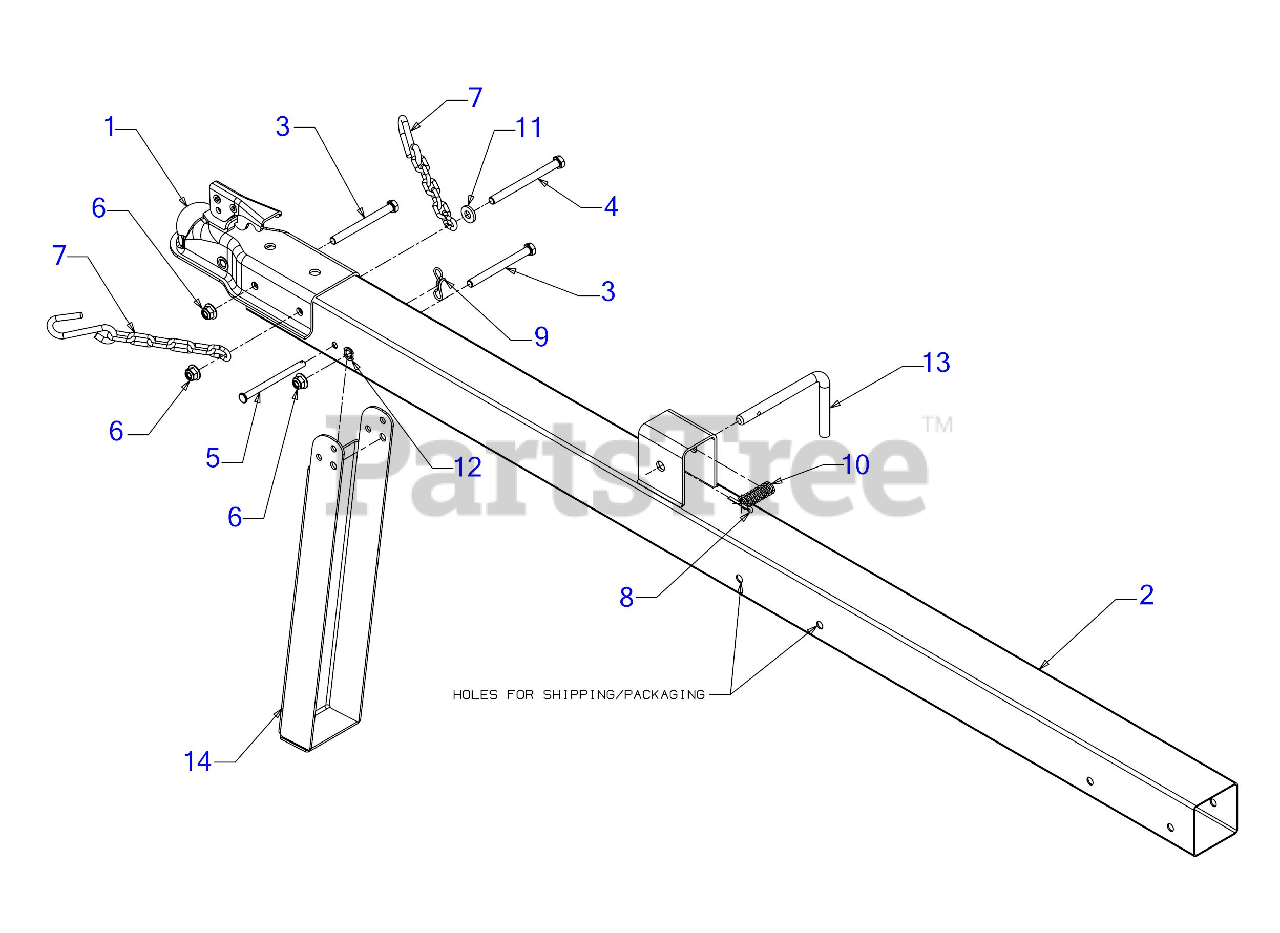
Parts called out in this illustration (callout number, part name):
1	HITCH COUPLING ASSEMBLY
4	SCREW 3/8 x 4.5 N.C GR. 5
5	CLEVIS PIN 5/16 x 4.135
7	LOGSPLITTER TOW CHAIN
8	COTTER PIN-5/32 DIA
9	PIN:COTTER
10	COMPRESSION SPRING
11	FLAT WASHER
12	BUSHING .380 ID
13	LATCH ROD
